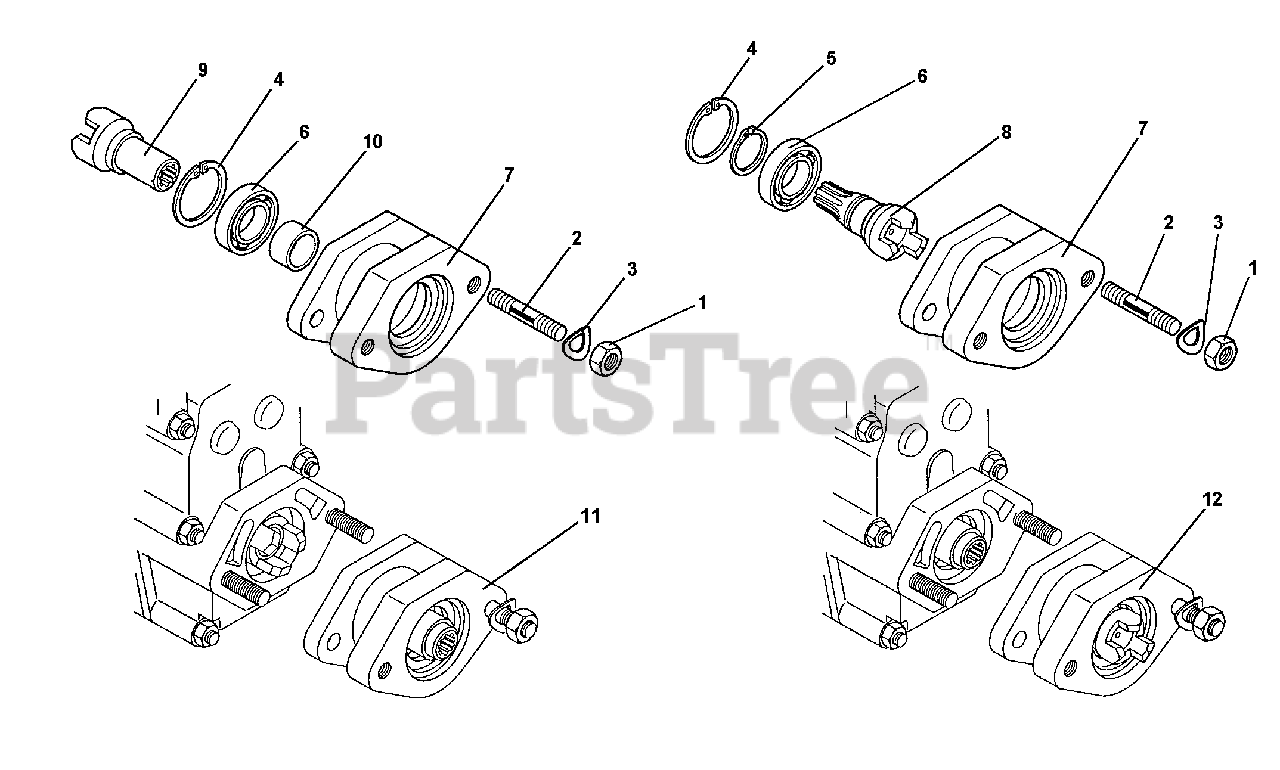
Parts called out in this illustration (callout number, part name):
1	NUT, SELF LOCKING M12
2	STUD, M12 X 1.25 X 12 X 52
3	WASHER, LOCK M13
4	CIRCLIP, INTERNAL
5	CIRCLIP, EXTERNAL
6	BEARING, M25 X 47 X 12
11	ADAPTER, NEW TRACTOR OLD ATT.
12	ADAPTER, OLD TRACTOR NEW ATT.
